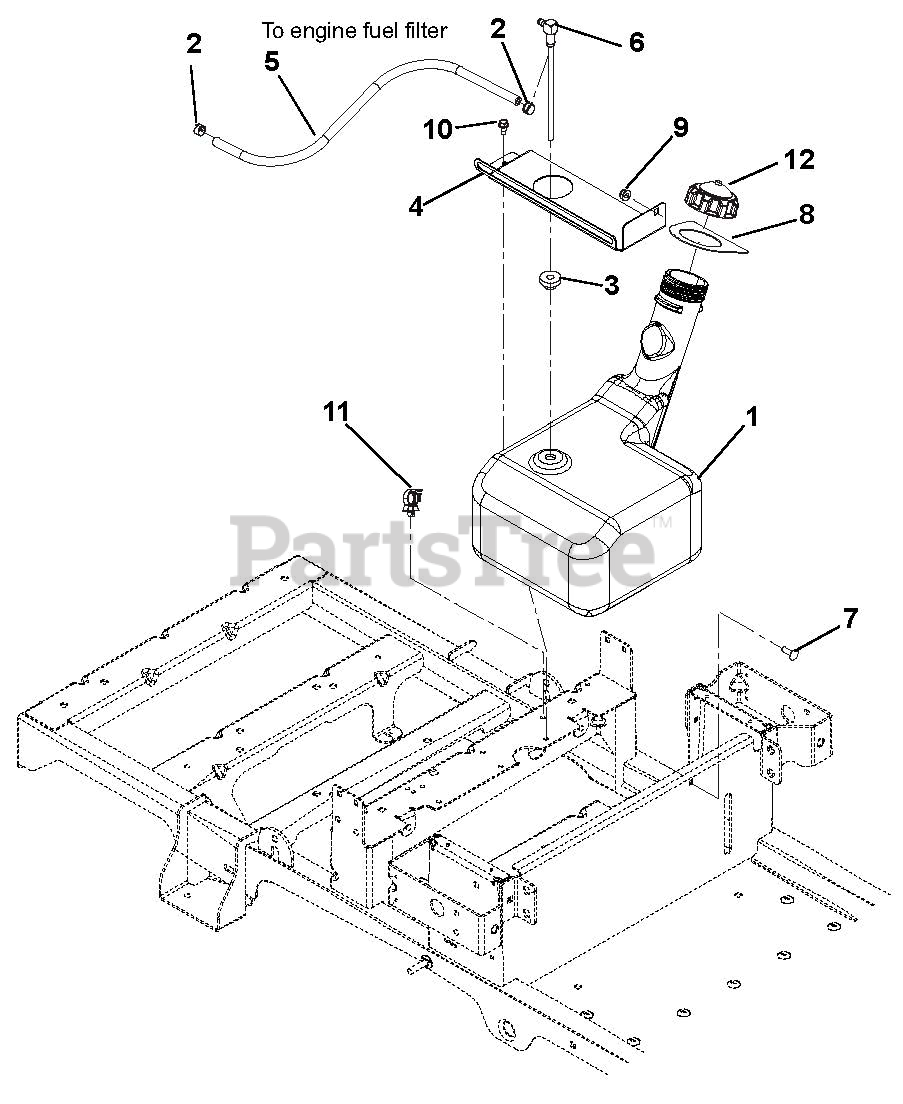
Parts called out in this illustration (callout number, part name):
1	FUEL TANK
2	CLAMP, FUEL LINE
3	BSHG-FLG .375X1.062X.625 NITR
4	BRKT, TANK STRAP
5	HOSE, .25 LOW-PERM BULK GAS
6	FUEL PICK UP TUBE
7	BLT, RHSN .25-20X.750 G5 ZCC
8	SEAL-TANK NECK
9	NUT,NYL-FLG .25-20 GF ZCC
10	SCR-TAP .25-20X.50 HWH ZCC
11	WIRE CLIP
12	FUEL CAP
